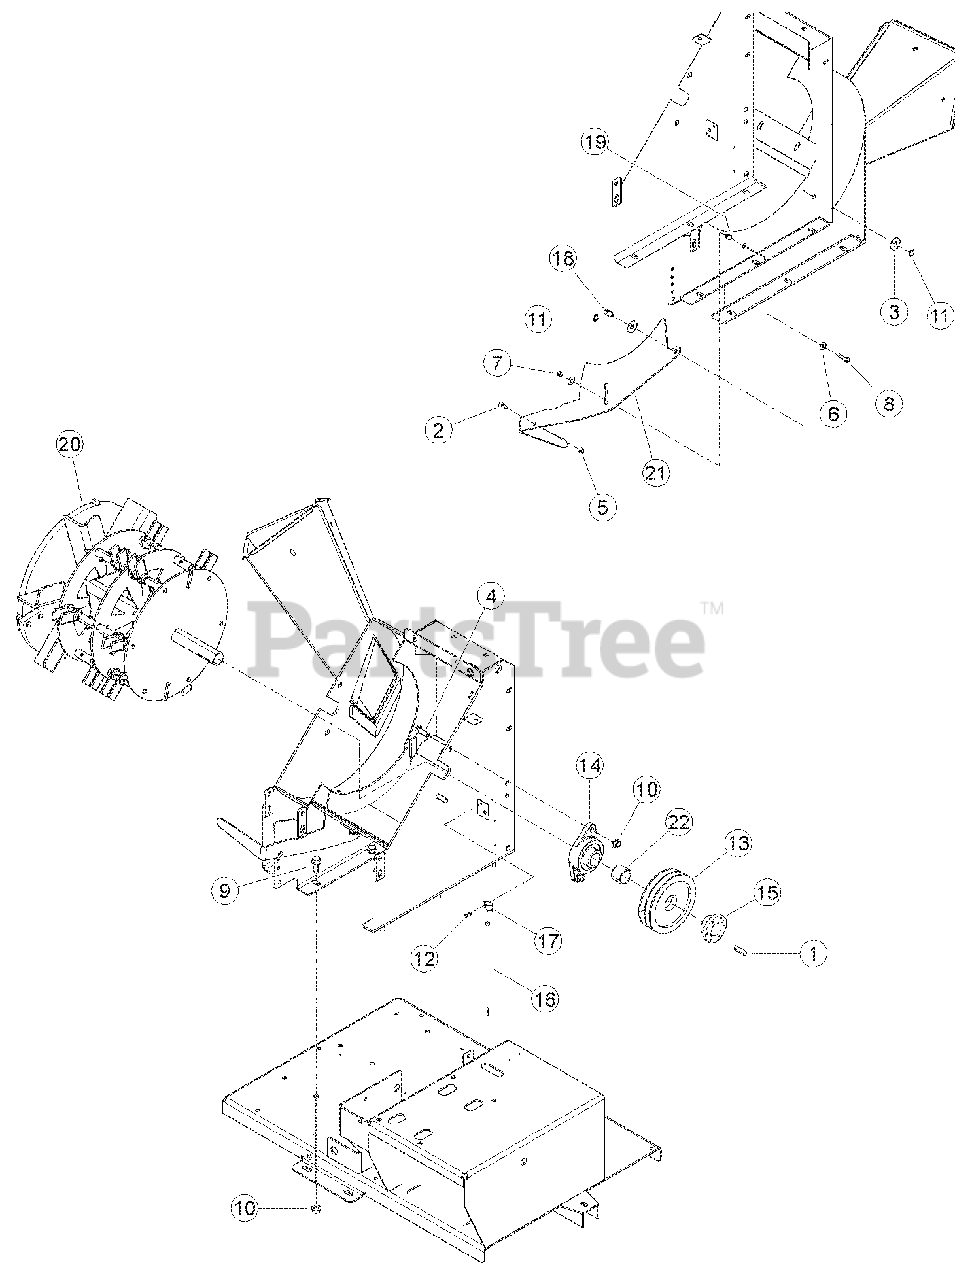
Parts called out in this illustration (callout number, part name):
1	KEY, 3/8 SQUARE X 1-1/2 LONG
2	BOLT, 5/16 X 3/4 HEX HD GR5 ZP
3	WASHER, 1/2 FLAT ZP
4	BOLT, 1/2 X 1-1/2 CRG GR5 ZP
5	NUT, 5/16 CENTERLOCK NC ZP
6	WASHER, 5/16 FLAT ZP
7	NUT, 5/16 NE NYLOCK ZP
8	BOLT, 5/16 X 1-1/4 HEX HD GR5 NC ZP
9	BOLT, 1/2 X 1-1/4 SERR FLANGE
10	NUT, 1/2 SERR FLZNGE NC ZP
11	CLIP, 1/2" E
12	RIVET, AL BLIND 1/4 X 3/4 DOME HEAD
13	SHEAVE 2B 6.6 SDS
14	BEARING,2 BOLT FLANGE 1-1/2" BORE
15	BUSHING, SDS 1-1/2"
16	STRAP, 11 IN BLACK TIE
17	CLAMP, CABLE MOUNT
18	PIN, RETAINER
19	SPACER, .50 X .50
20	ASSEMBLY, 5 INCH C/S ROTOR (REPLACED AND SUPERSEDED. FOR SERVICE ORDER PN77612-00, ROTOR REPLACEMENT KIT)
21	ADJUSTOR, SHREDDER
22	SPACER, 1-3/4" OD X 1-1/2" ID X 1-1/4"
